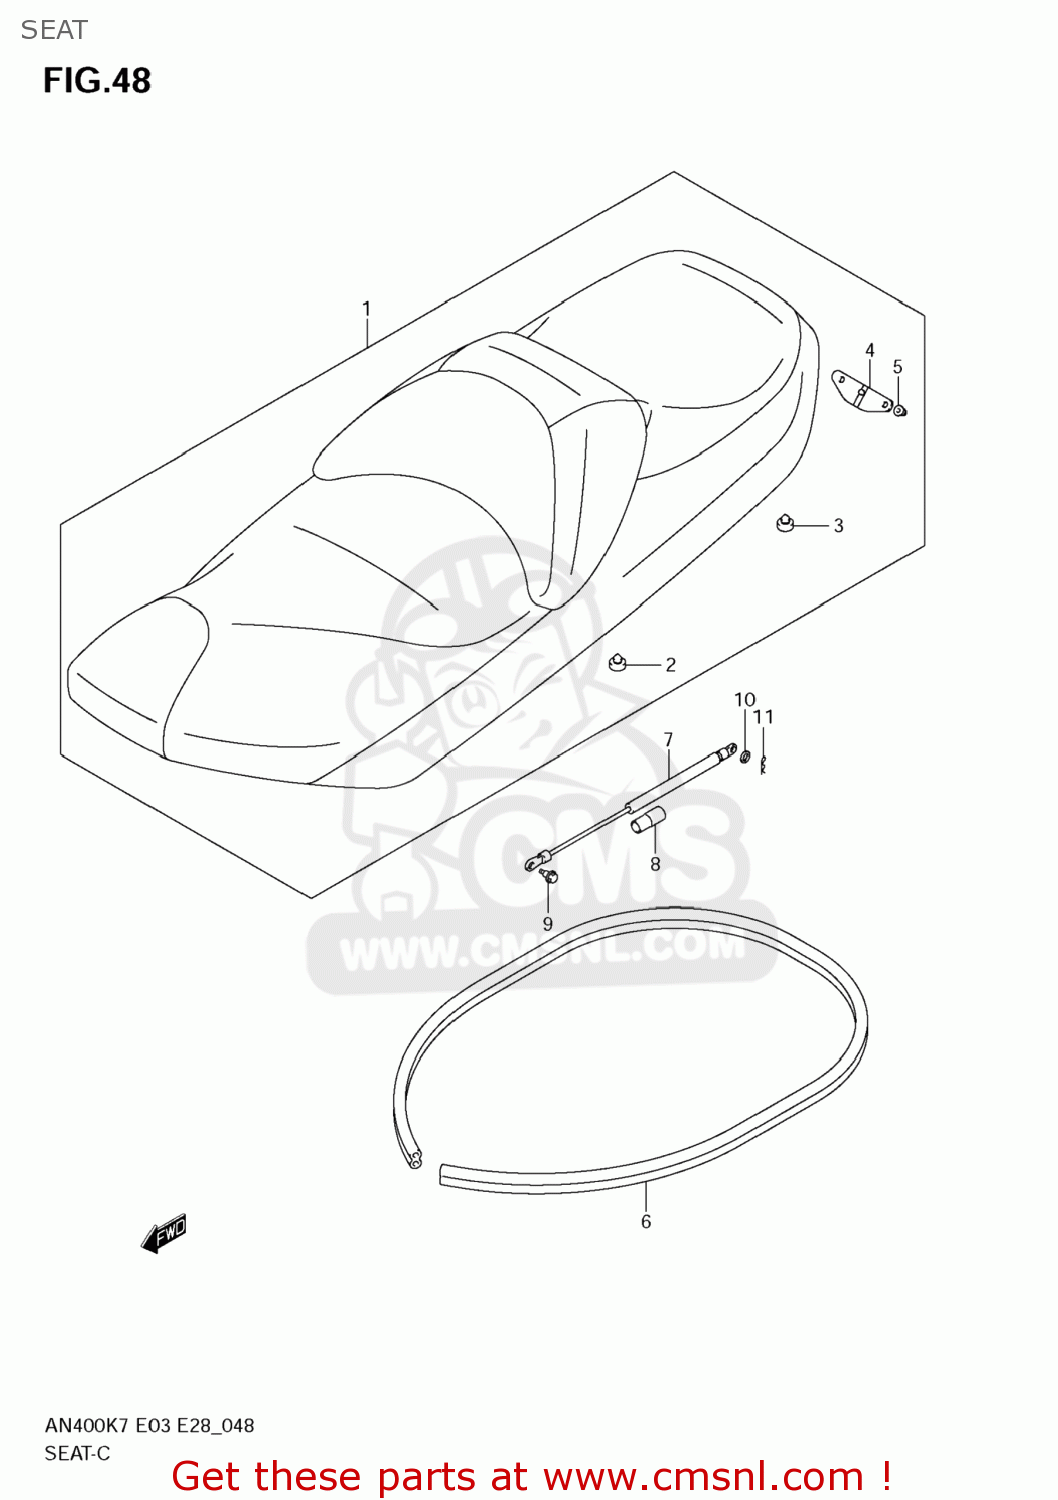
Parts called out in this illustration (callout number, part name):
1	SEAT ASSY
2	CUSHION
3	CUSHION,FR
4	STRIKER,SEAT LOCK
5	NUT
6	MOLDING,SEAT
7	DAMPER ASSY,SEAT
8	HOSE(13.5X16.5X600)
9	BOLT(6X16)
10	WASHER
11	SNAP
